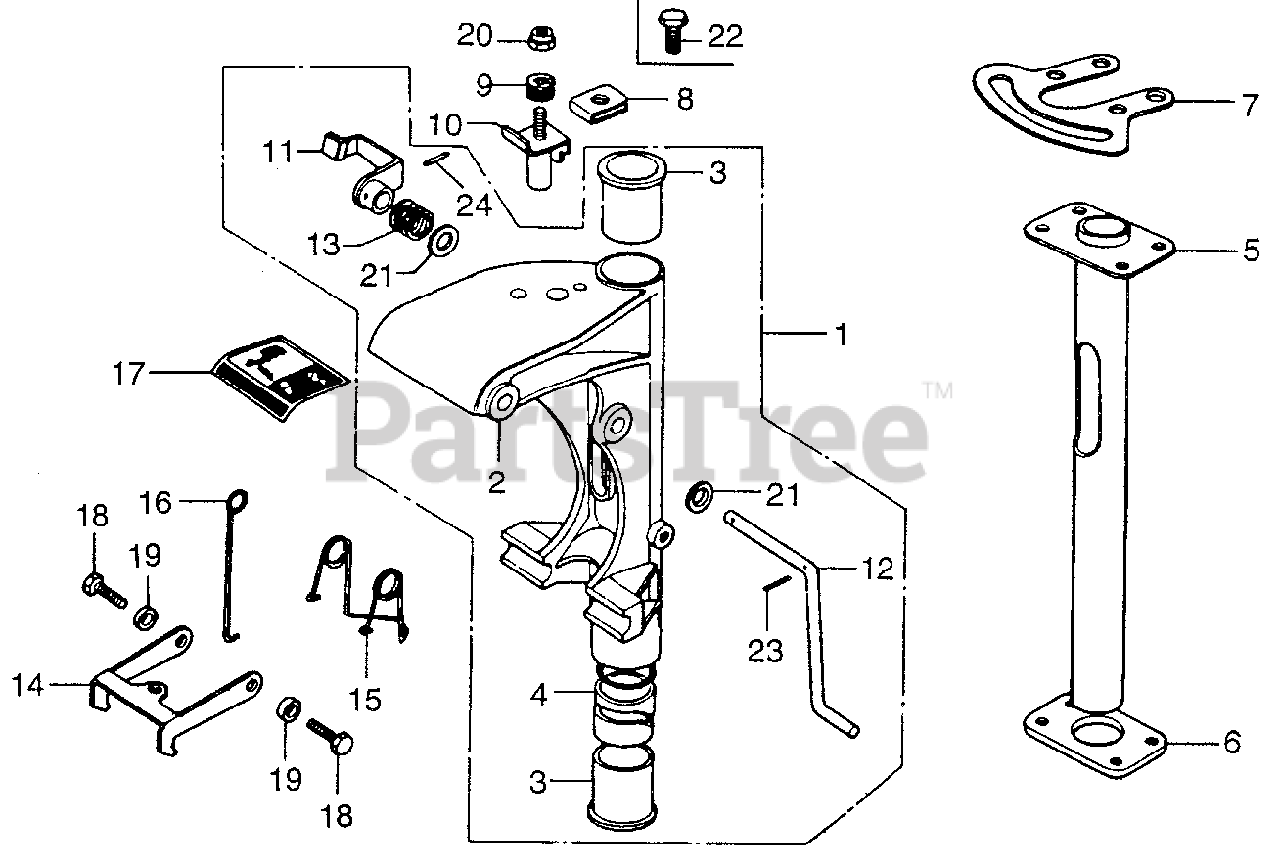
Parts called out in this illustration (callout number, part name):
1	CASE ASSY., SWIVEL *PB1* (DARK BLUE)
2	CASE, SWIVEL *PB1* (DARK BLUE)
3	BUSH, SWIVEL CASE (NOT AVAILABLE)
4	BUSH, SWIVEL CASE CENTER (N/A: SEE ASSEMBLY)
5	SHAFT, SWIVEL (NOT AVAILABLE)
6	FLANGE (LOWER)
7	PLATE, FRICTION
8	SHOE, FRICTION
9	SPRING, FRICTION (NOT AVAILABLE)
10	STATOR, FRICTION
11	LEVER, TILT (N/A: SEE ASSEMBLY)
12	LINK, L. TILT (NOT AVAILABLE)
13	SPRING, TILT
14	HOOK, REVERSE LOCK
15	SPRING, HOOK RETURN
16	ROD, RELEASE (NOT AVAILABLE)
17	PLATE, SETTING CAUTION
18	BOLT, FLANGE (6X12)
19	COLLAR (6MM) (NOT AVAILABLE)
20	NUT, FRICTION (6MM) (NOT AVAILABLE)
21	WASHER, PLAIN (10MM)
23	PIN, SPRING (2X20) (NOT AVAILABLE)
24	PIN, SPRING (4X14)
